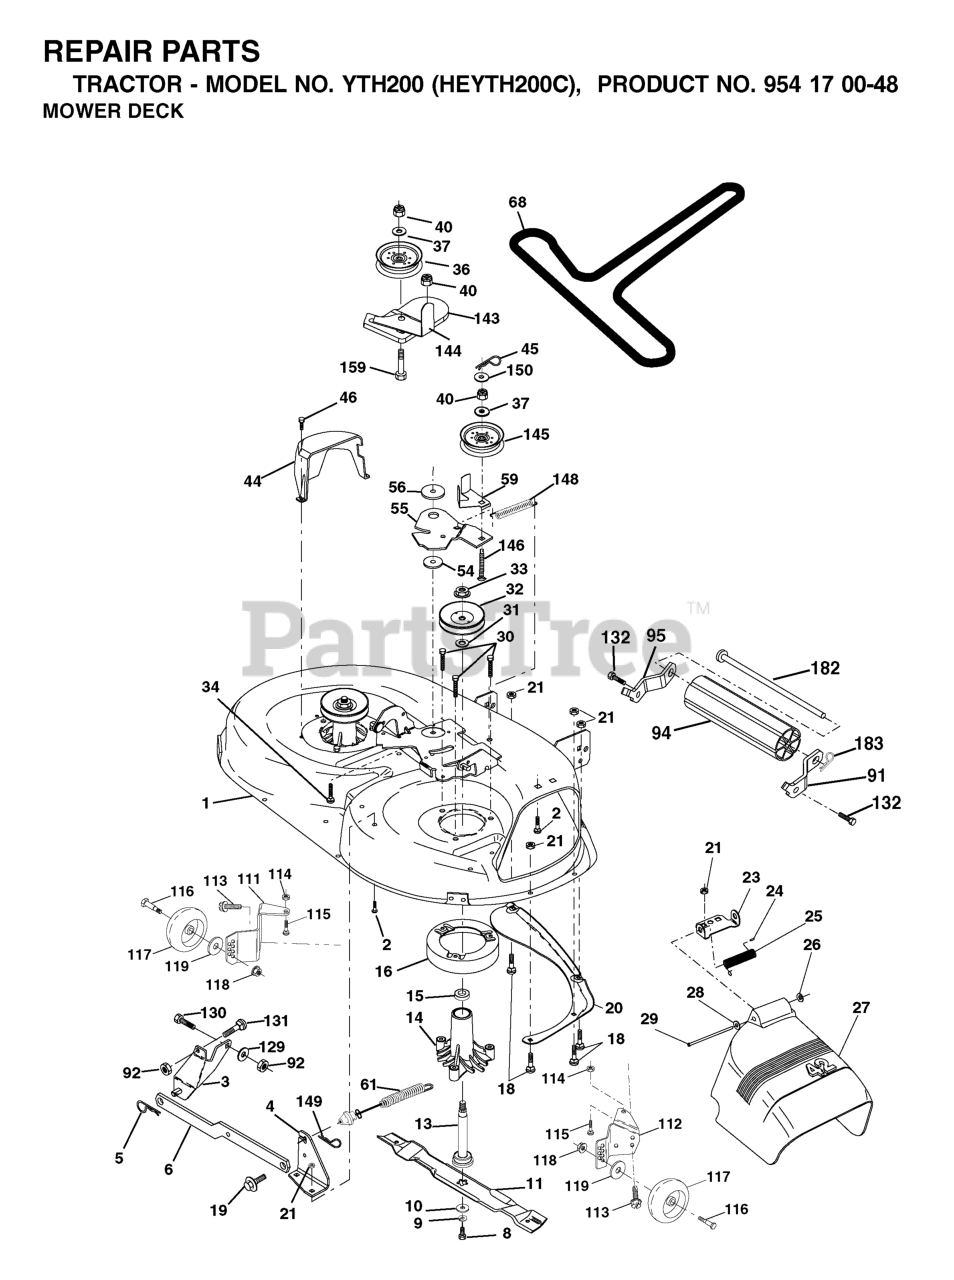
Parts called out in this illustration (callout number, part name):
1	42" DECK KIT
2	RP BOLT 5/16-18 X3/4 ZN/YEL GR
3	BRKT ASM SWAY BAR
4	BRACKET SWAY BAR 42" DECK
5	RETAINER-SPRNG RB
6	BAR SWAY DECK
8	BLADE BOLT
9	LOCKWASHER
10	WASHER.BLADE
11	Blade Mower 42" High Perf.
13	SHAFT ASM VENT
14	HOUSING.MANDREL.VENTED (MACHD)
16	STRIPPER.MANDREL.ROUND.BLACK
18	BOLT
19	BOLT SHD 5/16-18
20	BAFFLE.VORTEX
21	LOCKNUT
23	BRKT, DEFL. MOWER
24	CAP-SLEEVE LT
25	SPRING TORSION
26	NUT PUSH M
27	SHIELD DEFLECTOR
28	Washer 11/32 x 5/8 x 16 Ga SD
29	ROD.HINGE
30	SCREW, WASHER HEAD
31	WASHER
32	PULLEY/MANDREL
33	NUT, FLG TOPLOCK 9/16"
36	FLAT IDLER PULLEY
37	WASHER
44	GUARD MANDREL LH BLACK
45	RETAINER M
46	SCREW.1/4-20X5/8
54	HARDENED WASHER
55	ARM IDLER 42" MOWER LT/YT
56	SPACER.RETAINER.MOWER
59	GUARD, BELT
61	SPRING EXT ELEC CLUTCH
91	BRACKET ASM NOSEROLLER LH
92	NUT
94	NOSE ROLLER
95	BRACKET ASM NOSEROLLER RH
111	BRACKET, WHEEL
112	BRACKET, WHEEL
113	Screw Tapping 3/8-16 x .625
114	NUT
115	BOLT.CARR.5/16-18X5/8.SHORT
116	BOLT M
117	WHEEL.GAUGE.STANDARD
118	LOCKNUT
119	WASHER.5/16.FLAT.STE.STD.
129	WASHER
131	BOLT D
132	SCREW 3/8-16X3/4
143	BRACKET, ARM IDLER
144	DNO KEEPER.BELT.42".CLUTCH.CBL
145	PULLEY
146	BOLT, CARRIAGE IDLER BLACK
148	IDLER RETURN SPRING
149	SPRING.RETAINER.YELLOW.ZINC
182	ROD ROLLER NOSE STANDARD
183	SPRING RETAINER
